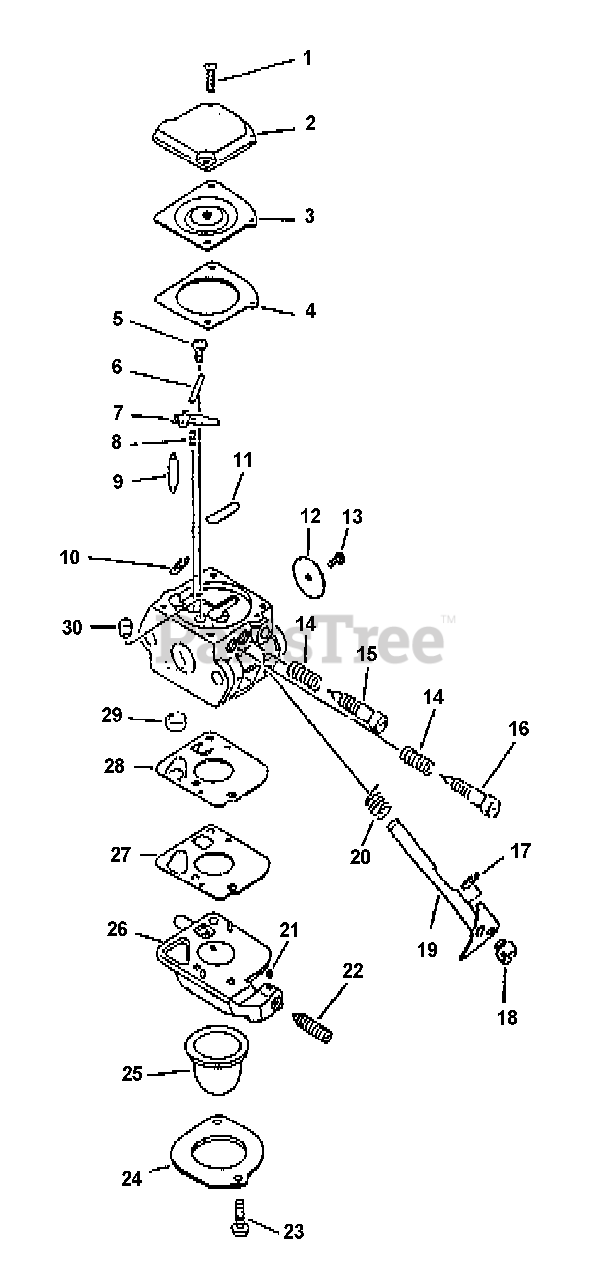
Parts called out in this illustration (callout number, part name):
2	COVER, METERING
3	DIAPHRAGM, METERING
4	GASKET, METERING
5	SCREW, METERING LEVER PIN
6	PIN, METERING LEVER
7	LEVER, METERING
8	SPRING, METERING LEVER
9	VALVE, THROTTLE
10	RING, RETAINING
11	PLUG, WELCH
12	VALVE, THROTTLE
15	NEEDLE - LOW SPEED
16	NEEDLE - MIXTURE
17	RING, RETAINING
19	SHAFT, THROTTLE
20	SPRING, RETURN
21	PIECE, FRICTION
22	SCREW, IDLE ADJUST
23	SCREW, RETAINER
24	RETAINER, PURGE BULB
25	BULB, PURGE
26	BASE, PURGE
27	GASKET, PURGE
28	DIAPHRAGM, PURGE
29	STRAINER
30	NOZZLE, CHECK VALVE
